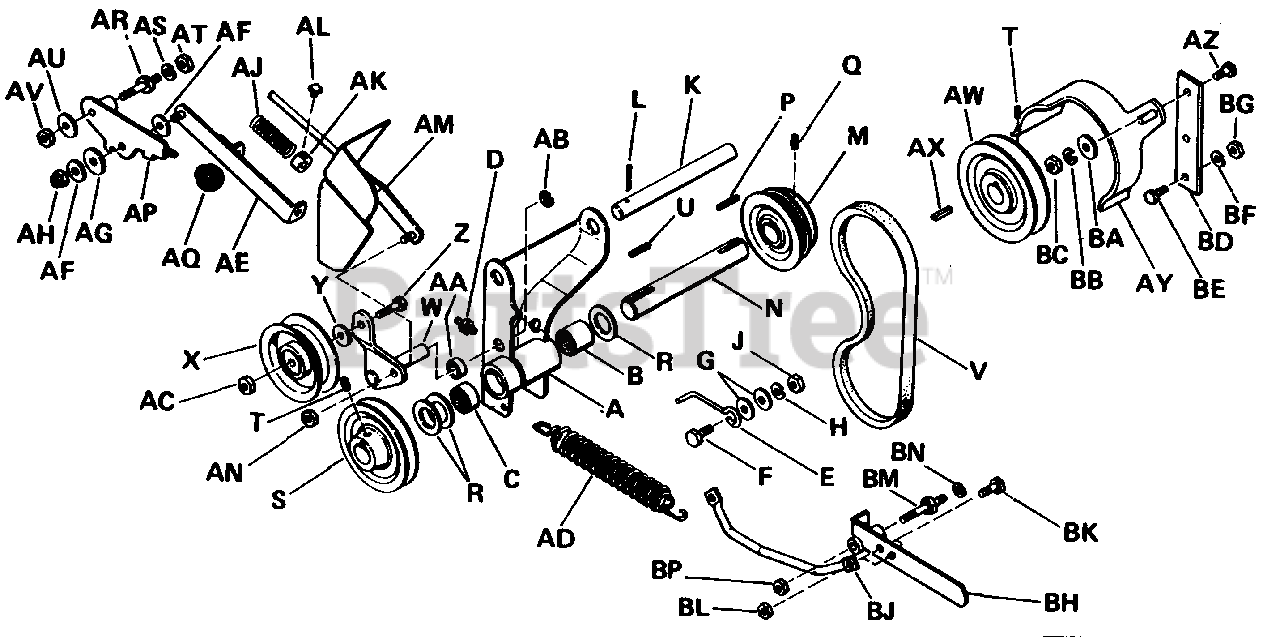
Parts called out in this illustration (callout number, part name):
A	Bracket, P.T.O. Ass'y.
B	Bearing, Roller
C	Bearing, Roller
D	Grease Fitting
F	Hex. Hd. Cap Screw, 5/16"-18 N.C. x 1" Lg.
G	Plain Washer, 5/16"
H	Lock Washer, 5/16"
J	Full Hex. Nut, 5/16"-18 N.C.
K	Rod Pivot, 5/8" Dia. x 6-13/16"
L	Cotter Pin
N	Shaft, P.T.O.
Q	Cup Pt. Skt. Hd. Screw Set, 5/16" 18 N.C.x 1/4" Lg.
S	Pulley, P.T.O.
T	Cup Pt. Skt. Hd. Screw Set, 5/16" 18 N.C. x 5/16" Lg.
V	BELT, 4L, 29.16"
W	Idler Lever Ass'y.
X	Idler Pulley
Y	Plain Washer, 5/16"
Z	Hex. Cap Screw, 3/8"-16 N.C. x 1-1/4"
AB	Retaining Ring
AC	Full Lock Hex. Nut, 3/8"-16 N.C.
AD	Spring, Tension
AE	Rod Guide Ass'y.
AF	Plain Washer, 5/16"
AG	Washer, Special
AH	Elastic Stop Nut, 5/16"-18 N.C.
AL	Cup Pt. Sq. Hd. Screw Set, 1/4"-20 N.C. x 3/8" Lg.
AM	Rod Guide Assembly
AN	Full Lock Hex. Nut, 3/8"-16 N.C.
AP	Clutch Lever Ass'y, P.T.O.
AQ	Knob, P.T.O.
AS	Lock Washer, 3/8"
AT	Full Hex. Nut, 3/8"-16 N.C.
AU	Plain Washer, 5/16"
AV	Stop Center Lock Jam Nut, 3/8"-16
AY	Guard Belt
AZ	Hex. Cap Screw, 3/8"-16 N.C. x 1"
BA	Plain Washer, 3/8"
BB	Lock Washer, 3/8"
BC	Full Hex. Nut, 3/8"-16 N.C.
BD	Guard Belt Support, 3/16" x 1 1/4" x 5 7/16" Lg.
BE	Hex. Cap Screw, 5/16"-18 N.C. x 1"
BF	Lock Washer, 5/16"
BG	Full Hex Nut, 5/16"-18 N.C.
BH	Handle Ass'y.
BJ	Spring Tension Rod
BK	Hex. Cap Screw, 5/16"-18 N.C. x 3/4"
BL	Full Lock Hex. Nut, 5/16"-18 N.C.
BN	Lock Washer, 7/16"
BP	Full Lock Hex. Nut, 7/16"-14 N.C.
